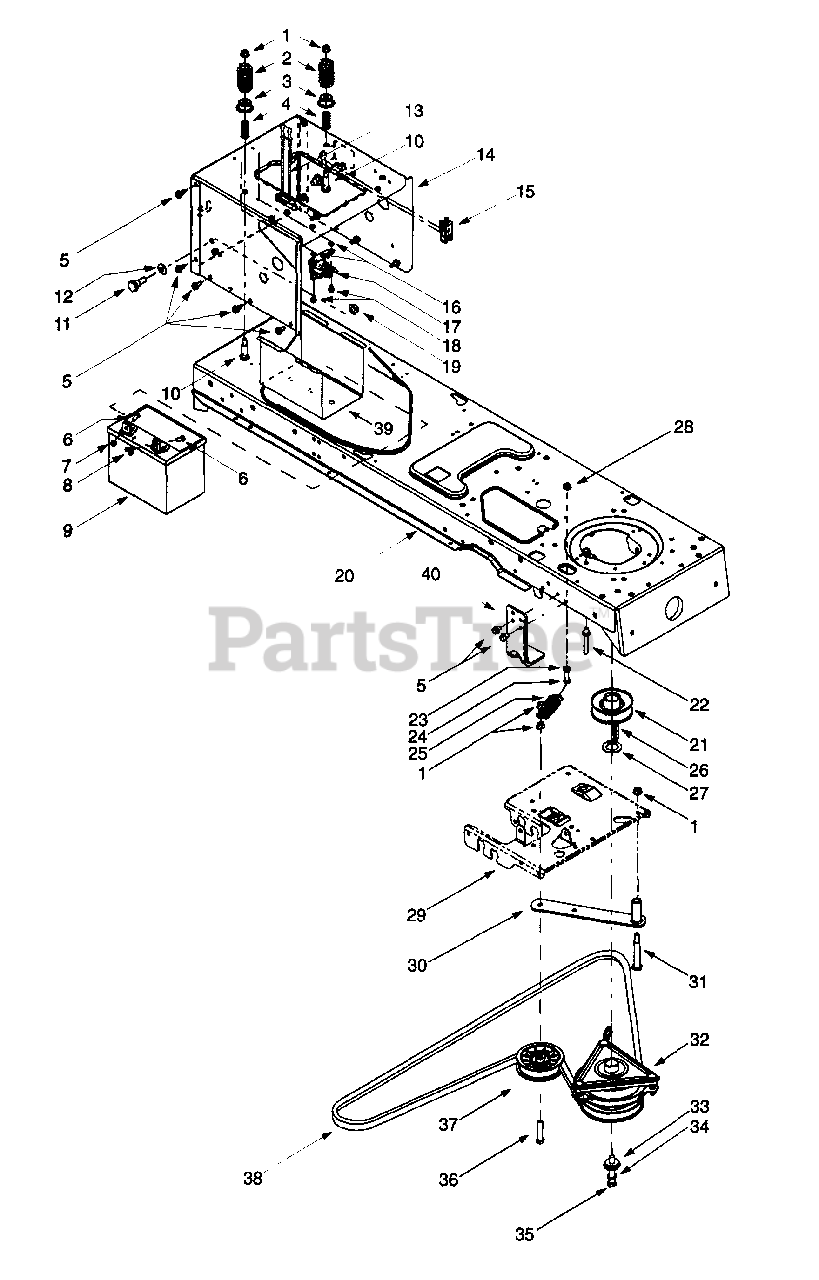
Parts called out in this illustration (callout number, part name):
1	Range Lock Nut, 3/8-16
2	Compression Spring, 1.318 x 2.37
3	Spacer Cup, 1.5 OD
4	Compression Spring, .66 OD x 1.5
5	Self Tapping Screw, 5/16-18 x .625
6	Hex Cap Screw, 1/4-20 x .62
7	Hex Sems Nut, 1/4-20
8	Wing Nut, 1/4-20
9	12-volt Battery, 270 CCA
10	Shoulder Screw, .5 x 1.25, 3/8-16
11	Shoulder Screw, .625 x .5, 7/16-20
12	Bell Washer, .45 x 1.0 x .062
13	Battery Strap
16	Lock Washer, 1/4
17	Solenoid, 12-Volt, 100 Amp
18	Self Tapping Screw, 1/4-20 x .5
19	Flange Lock Nut, 7/16-20
22	Stud, 3/8-16 x 2.68
23	Hex Nut, 5/16-18
24	Hex Cap Screw, 5/16-18 x 1.75 (Grade 5)
25	Extension Spring, 1.2 OD x 3.638
26	Square Key, 1/4 x 1.5
27	Flat Washer, 1.03 x 1.62 x .095
28	Flange Lock Nut, 5/16-18
31	Shoulder Screw, 1/2 Diameter x 2.5
32	Electric PTO Clutch
33	Shoulder Spacer, 1.38 x .445 x .36
34	Lock Washer, 7/16
35	Hex Cap Screw, 7/16-20 x 3.25 (Grade 5)
36	Hex Cap Screw, 3/8-16 x 2.25 (Grade 5)
37	Flat Idler Pulley, 3.5 OD
38	PTO Belt
